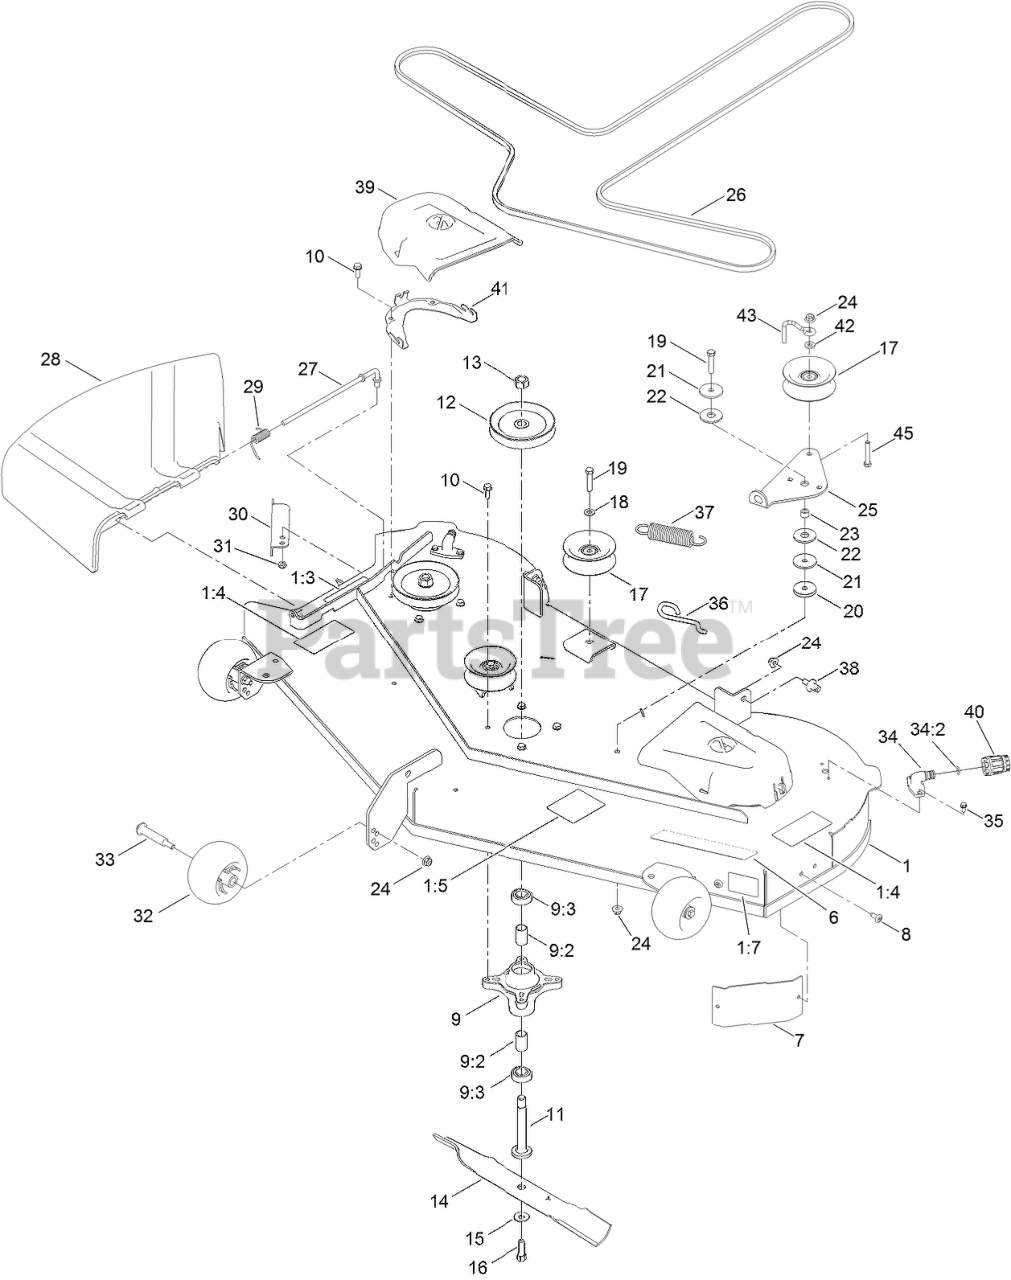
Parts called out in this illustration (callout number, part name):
1	54in DECK AND DECAL ASM
1:3	DECAL-DANGER
1:4	DECAL-DANGER, DECK
1:5	DECAL-ROUTING, BELT
1:7	DECAL-SCALP, ANTI
6	DECAL-DECK
7	BAFFLE-CORNER
9	SPINDLE ASM
9:2	SPACER
9:3	BEARING-BALL
10	SCREW-TAPTITE
11	SHAFT-SPINDLE
12	PULLEY ASM
13	NUT-HEX
14	BLADE-HI LIFT
15	WASHER-BELLEVILLE
16	SCREW-HH
17	PULLEY-IDLER, FLAT
18	WASHER-FLAT
19	SCREW-HH
20	WASHER-PLAIN
21	WASHER-REBOUND
22	WASHER-FRICTION, COMPOSITE
23	SPACER
24	NUT-HF, NI
25	ARM-IDLER
26	BELT-V
27	ROD-PIVOT
28	DEFLECTOR-DISCHARGE
29	SPRING-TORSION
30	BAFFLE-CUTOFF
32	ROLLER-SCALP, ANTI
33	BOLT-SHOULDER
34	FITTING-WASHOUT
34:2	O-RING
35	SCREW-HWH
36	HOOK-RETURN SPRING
37	SPRING-EXTENSION
38	PIN-DECK
39	COVER-BELT
40	CONNECTOR-HOSE
41	BRACKET-COVER, BELT
42	SPACER-HUB, BLOWER
43	BELT GUIDE - IDLER
45	SCREW-HH
